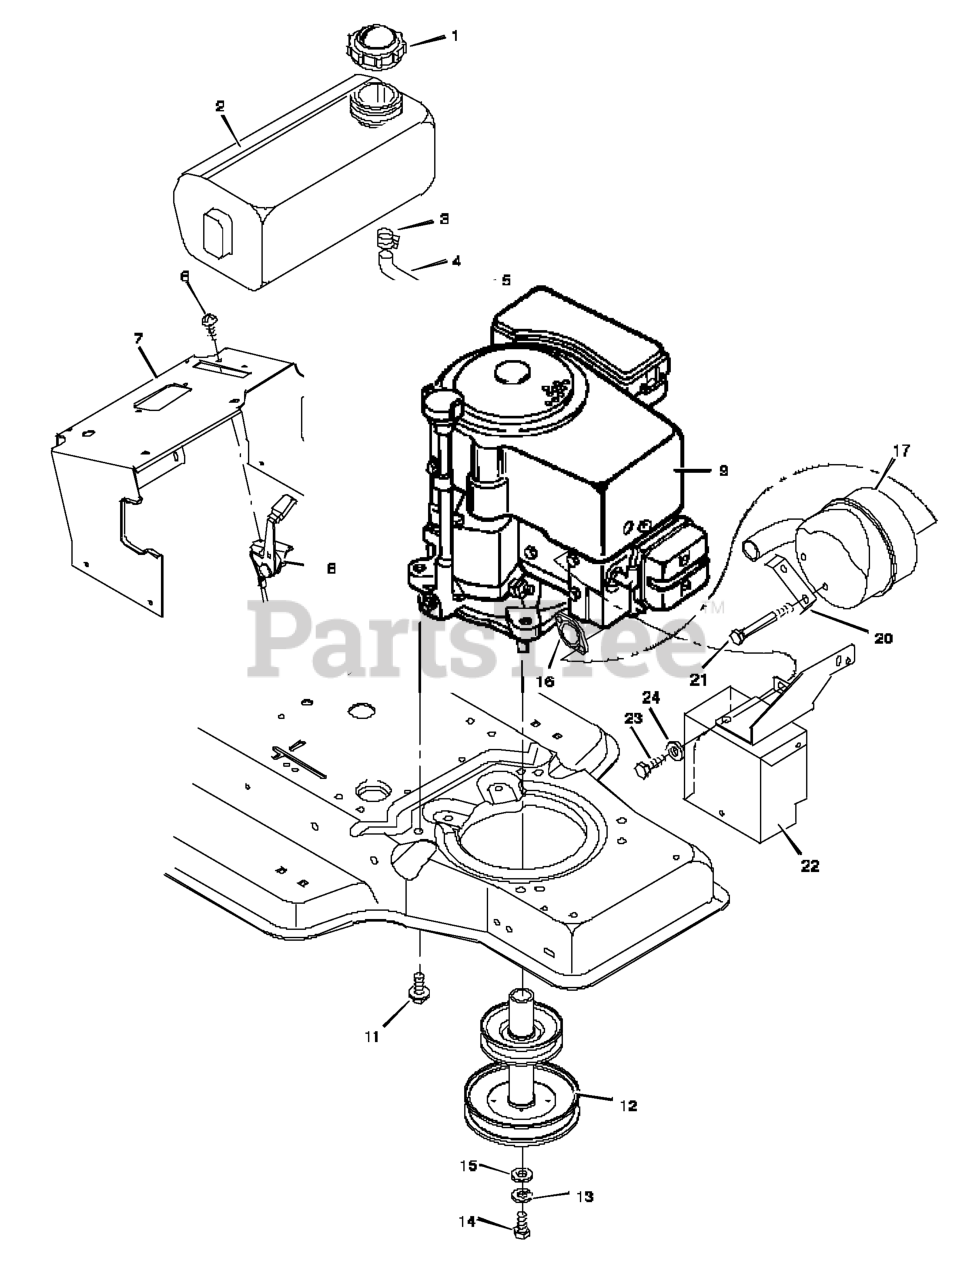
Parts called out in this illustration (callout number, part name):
1	Fuel Cap
2	Fuel Tank
3	Hose Clamp
4	Fuel Line
5	Hose Clamp
7	Support, Dash
8	Throttle Control
9	Engine *
11	Bolt, Engine Mount
12	Stack Pulley Assembly
13	Lockwasher
14	Bolt, Hex
16	GASKET, Exhaust
17	Muffler
20	Lock, Screw
22	Shield, Heat
